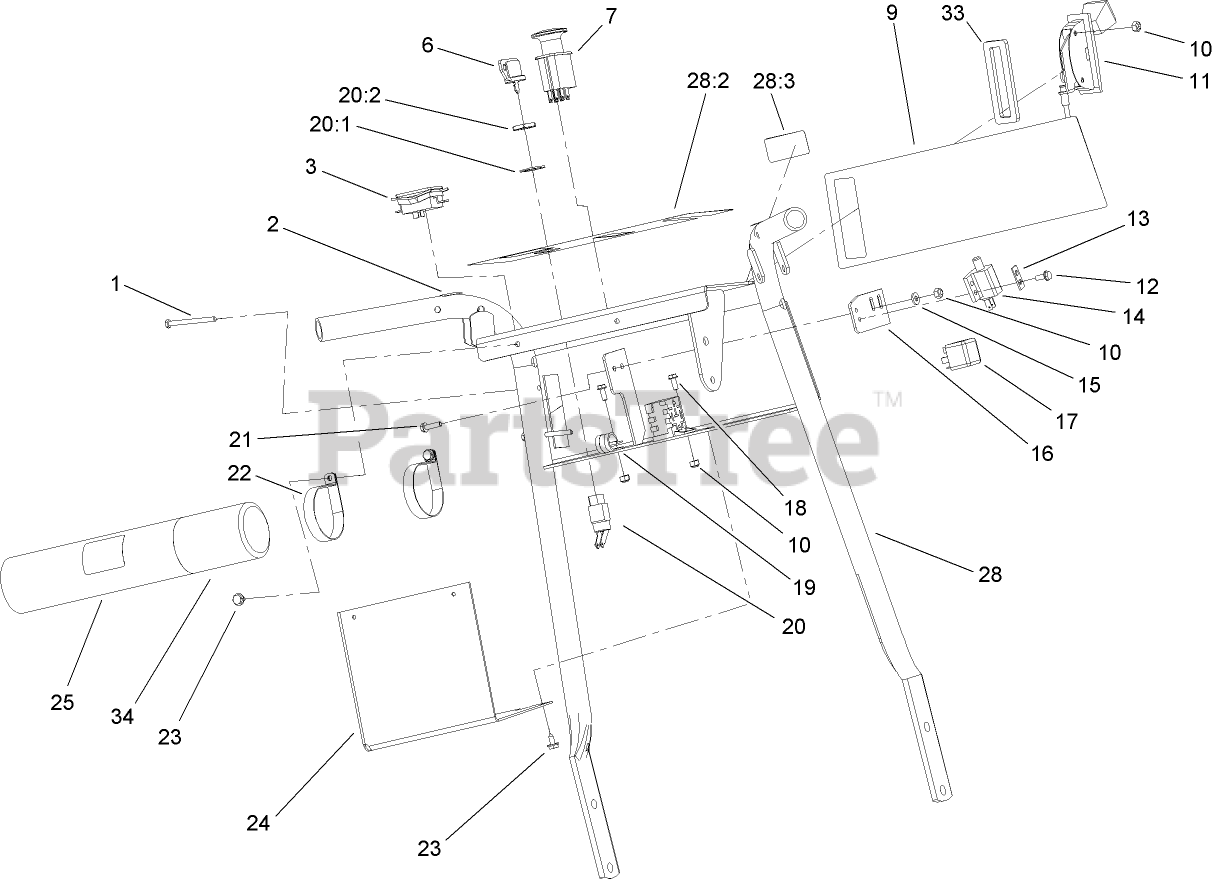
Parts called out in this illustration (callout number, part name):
1	SCREW-SHH
2	DECAL-LOCK, NEUTRAL
3	HOURMETER
6	KEY-IGNITION
7	SWITCH-PTO
9	DECAL-CONTROL, THROTTLE
10	NUT-LOCK, NI
11	CABLE-THROTTLE
12	SCREW-TAPTITE
13	PLATE-SWITCH
14	SWITCH-OPEN, NORMALLY
15	WASHER-FLAT
16	PLATE-MOUNTING, SWITCH
17	RELAY
18	SCREW-HWH
19	CLAMP-R
20	Key Switch ASM
20:1	WASHER-TOOTH, INTERNAL
20:2	NUT-HH
21	SCREW-HWH
22	CLAMP-R
23	SCREW-HWHTF
24	BRACKET-COVER
25	TUBE-MANUAL
28	HANDLE ASM
28:2	DECAL-PANEL, CONTROL
28:3	DECAL-PROTECTION, EAR
33	GASKET-THROTTLE
34	CAP-HOUSING
